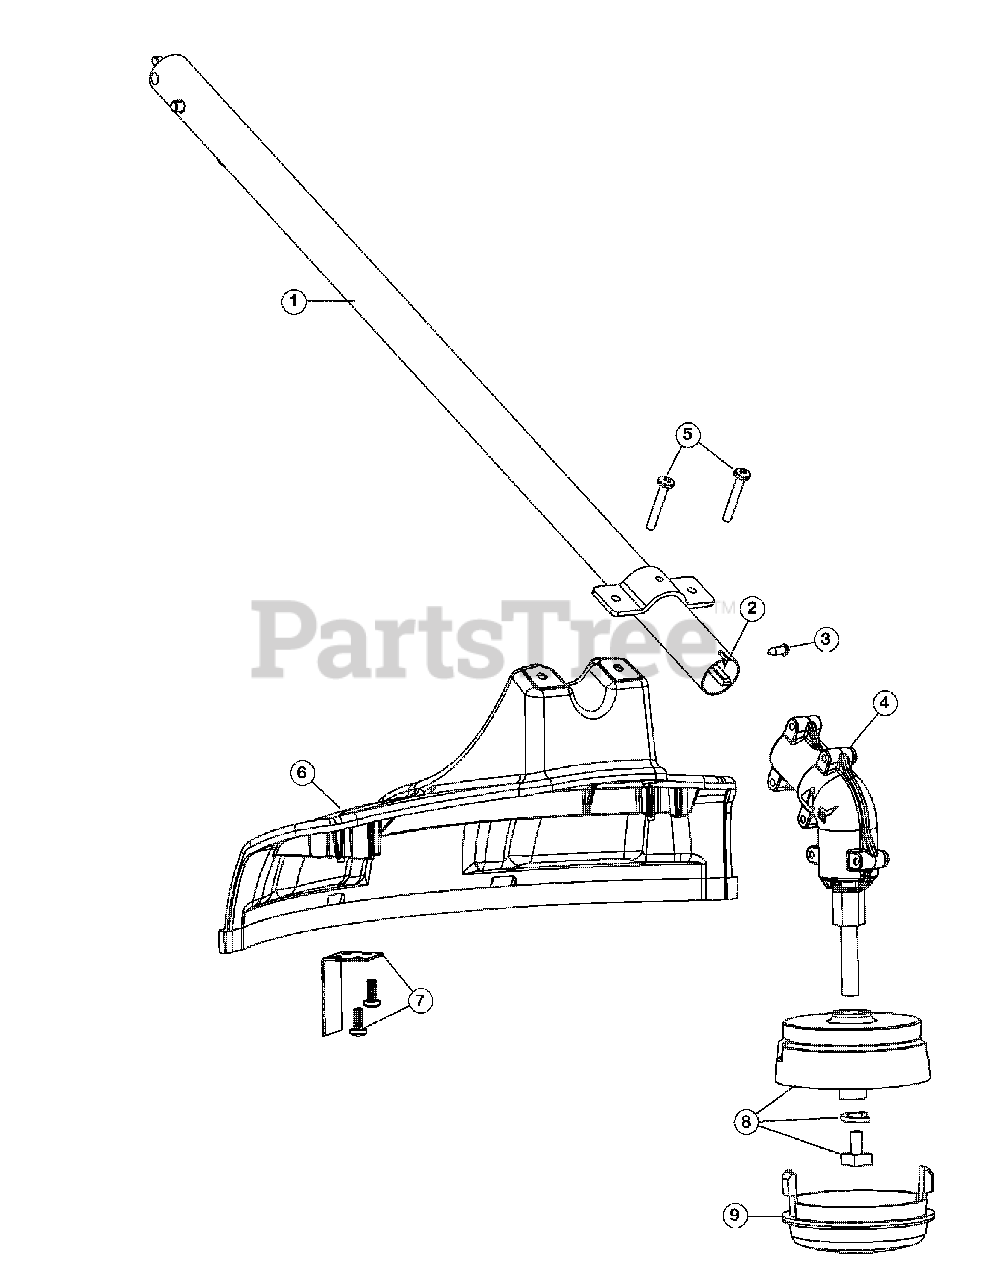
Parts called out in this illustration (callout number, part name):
1	Drive Shaft Housing Assembly
2	Flexible Drive Shaft
3	Anti-Rotation Screw
4	Gearbox Assembly
5	Guard Mounting Screws
6	Guard & Blade Assembly (Incl. Ref No. 7)
7	Blade Assembly
8	Cutting Head (Incl. Ref No. 9)
